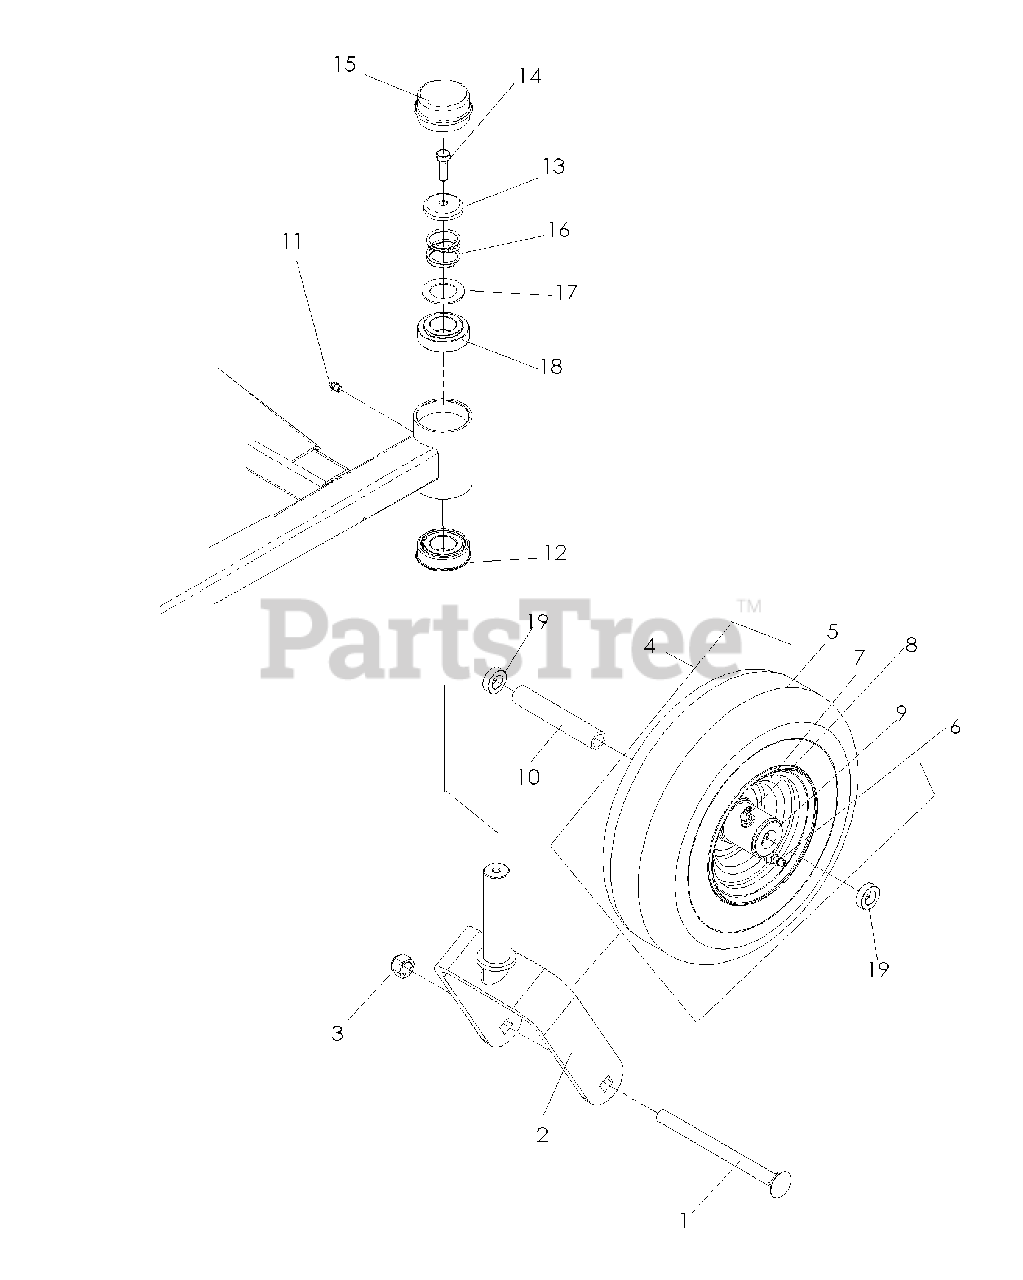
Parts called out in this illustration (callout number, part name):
1	RHSNB 1/2-13 X 6.50 GR2 ZD
2	CASTER DK BLUE
3	NUT 1/2-13 HEX NYLOC ZD
4	TIRE ASSEMBLY, BRG
5	TIRE.11"X4"-5.4PLY.SMOOTH.KEND
6	VALVE STEM TR-412
8	ZERK
9	BEARING RETAINER
11	ZERK, 3/16, DRIVE IN
12	BEARING FLANGED
13	CASTER.PLUG
14	HCS 5/16C X 1
15	GREASE CAP
16	SPRING, CASTER
17	WASHER, 1.025 ID X 1.64
18	BUSHING, CASTER
19	SPACER, 5/16"
